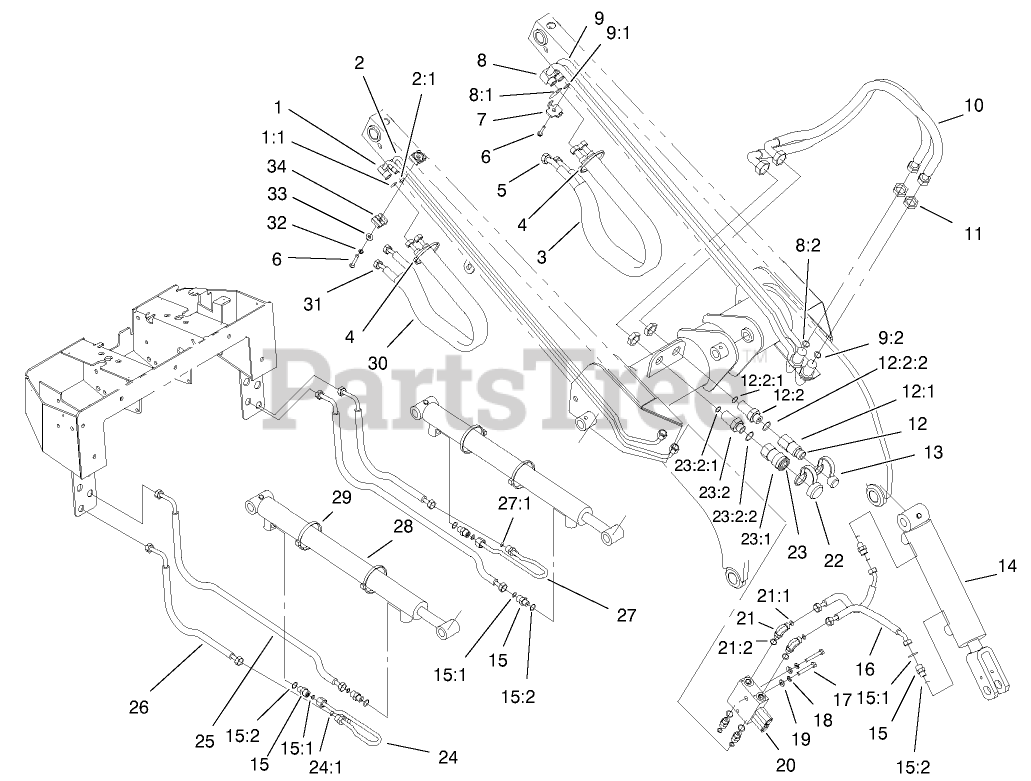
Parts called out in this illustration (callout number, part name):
1	HYDRAULIC TUBE ASM
1:1	O-RING
2	HYDRAULIC TUBE ASM
2:1	O-RING
3	SLEEVE-PROTECTIVE
4	TIE-CABLE
5	HOSE-HYD
6	SCREW-HWH
7	PLATE-CLAMP, TUBE
8	HYDRAULIC TUBE ASM
8:1	O-RING
8:2	O-RING
9	HYDRAULIC TUBE ASM
9:1	O-RING
9:2	O-RING
10	HOSE ASM
11	NUT-LOCK, BULKHEAD
12	BULKHEAD NIPPLE ASM
12:1	NIPPLE-FACE, FLUSH
12:2	FITTING-ADAPTER, BULKHEAD
12:2:1	O-RING
12:2:2	O-RING
13	CAP-DUST, NIPPLE
14	CYLINDER-TILT
15	Adapter
15:1	O-RING
15:2	O-RING
16	HOSE-HYD
17	SCREW-HH
18	WASHER-LOCK
19	WASHER-PLAIN
20	VALVE-RELIEF, CROSSOVER
20:1	SEAL KIT
20:2	CARTRIDGE-RELIEF
20:3	CARTRIDGE-RELIEF
21	FITTING-ELBOW, 90 DEG
21:1	O-RING
21:2	O-RING
22	CAP-DUST, COUPLER
23	BULKHEAD COUPLER ASM
23:1	COUPLER-FACE, FLUSH
23:2	FITTING-ADAPTER, BULKHEAD
23:2:1	O-RING
23:2:2	O-RING
24	HYD TUBE ASM
24:1	O-RING
25	HYD HOSE ASM
26	HOSE-HYD
27	HYD TUBE ASM
27:1	O-RING
28	CYLINDER-LIFT
29	TIE-CABLE
30	SLEEVE-PROTECTIVE
31	HOSE-HYD
32	WASHER-LOCK
33	WASHER-FLAT
34	CLAMP-TUBE
